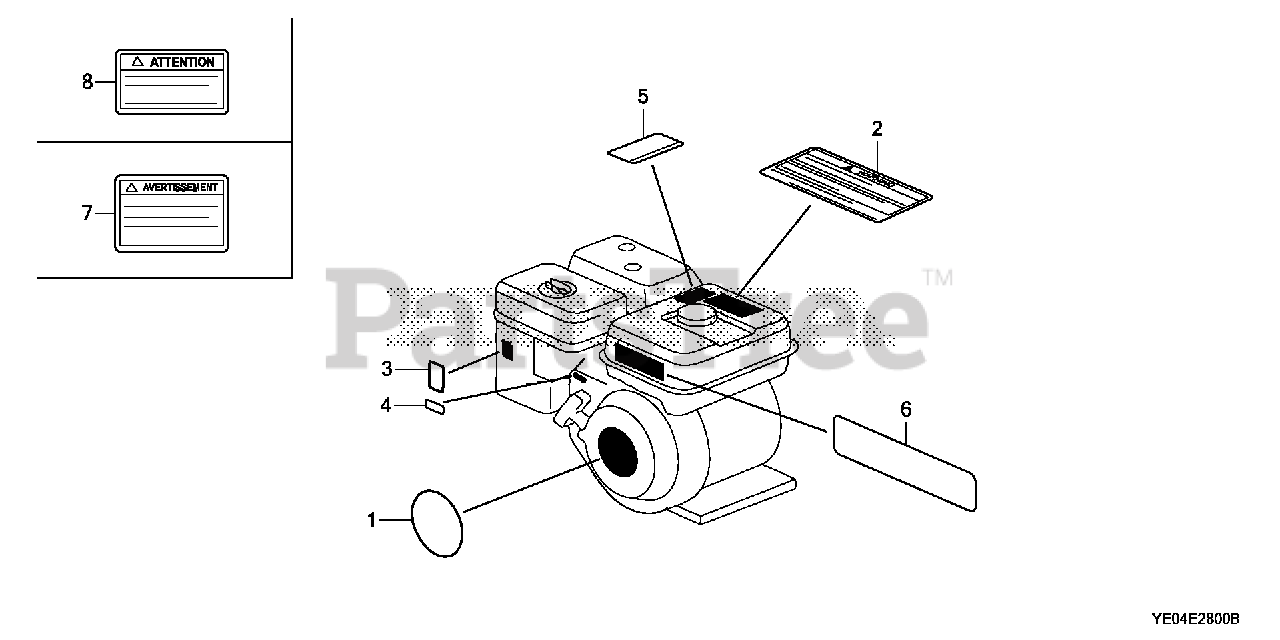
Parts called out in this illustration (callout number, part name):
1	EMBLEM (GX160)
2	MARK, OPERATOR CAUTION (ENGLISH)(MADE IN THAI)
3	MARK, CHOKE (GRAY)
4	MARK, THROTTLE INDICATION
5	MARK, EX. CAUTION (ENGLISH)
6	LABEL, CAUTION
